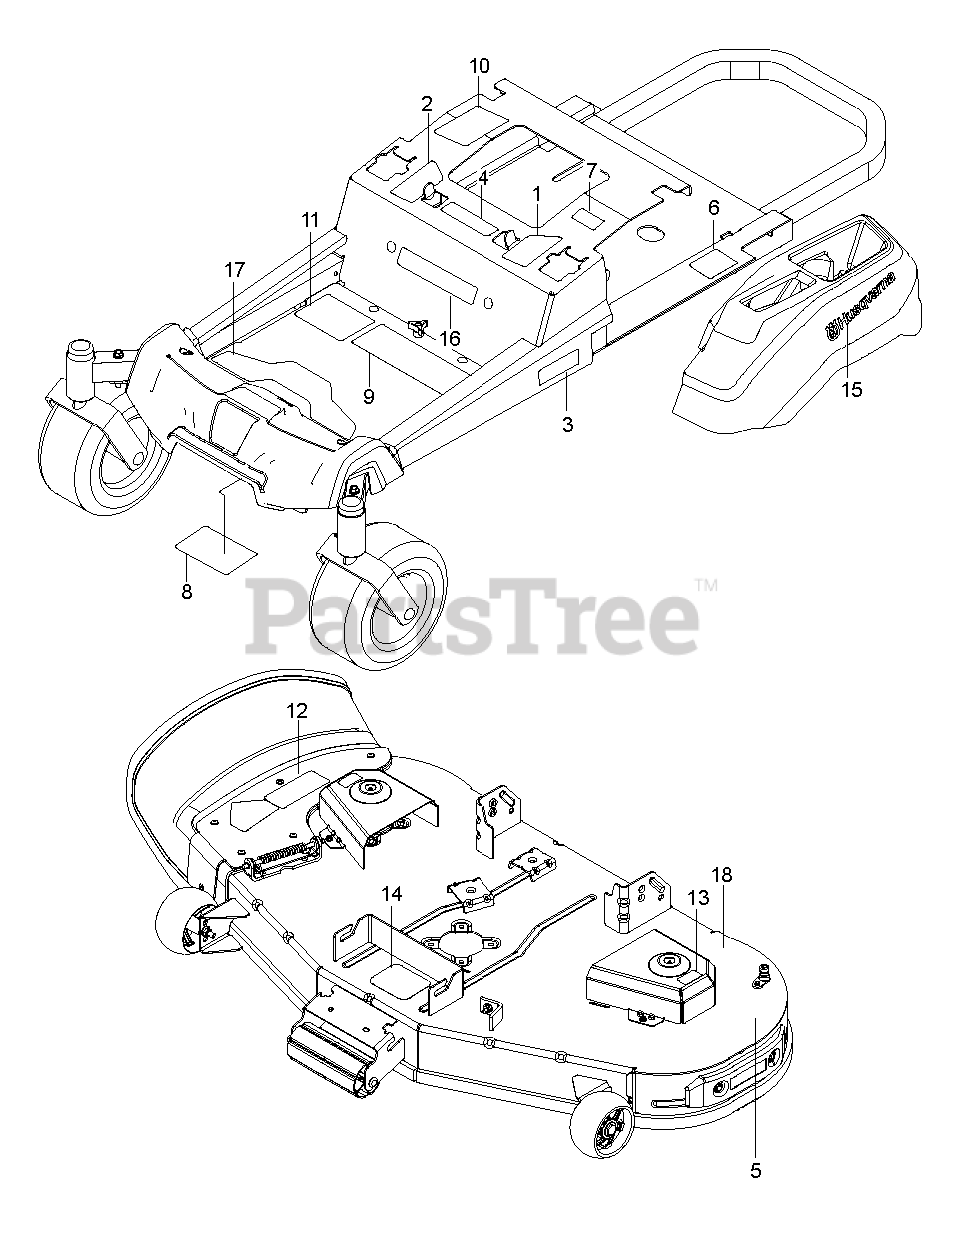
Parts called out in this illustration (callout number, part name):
1	DECAL.ZTR.RZ.THRTL/PRKBRK.V2.L
2	DECAL.ZTR.RZ.THRTL/PRKBRK.V2.R
3	DECAL.ZTR.SIDERAIL.MN.Z248F.HU
4	EURO DECAL-BATTERY WARNIN6
5	DECAL DECK DECAL DECAL.48DECK.
6	DECAL, DO NOT TOW
7	DECAL, EXITING MOWER
8	DECAL, SERVICE
9	DECAL ZTR WARNING DECAL DECAL.
10	DECAL.WARNING.CUST.RESP.E85.
11	DECAL.ZTR.STARTINSTRCT.CHOKE15
12	DECAL.TRACT/ZTR.DECKWARN.HUSQ
13	DECAL.DECK.CLEARCUT.NOSTEP
14	DECAL, BELT ROUTING
15	DECAL.HUSQVARNA.210MM
16	DECAL ZTR BRAND GRAPHIC DECAL.
17	PAD.RZ.FOOTREST.PLATE
18	DECAL DECK DECAL DECAL.DECK.WA
